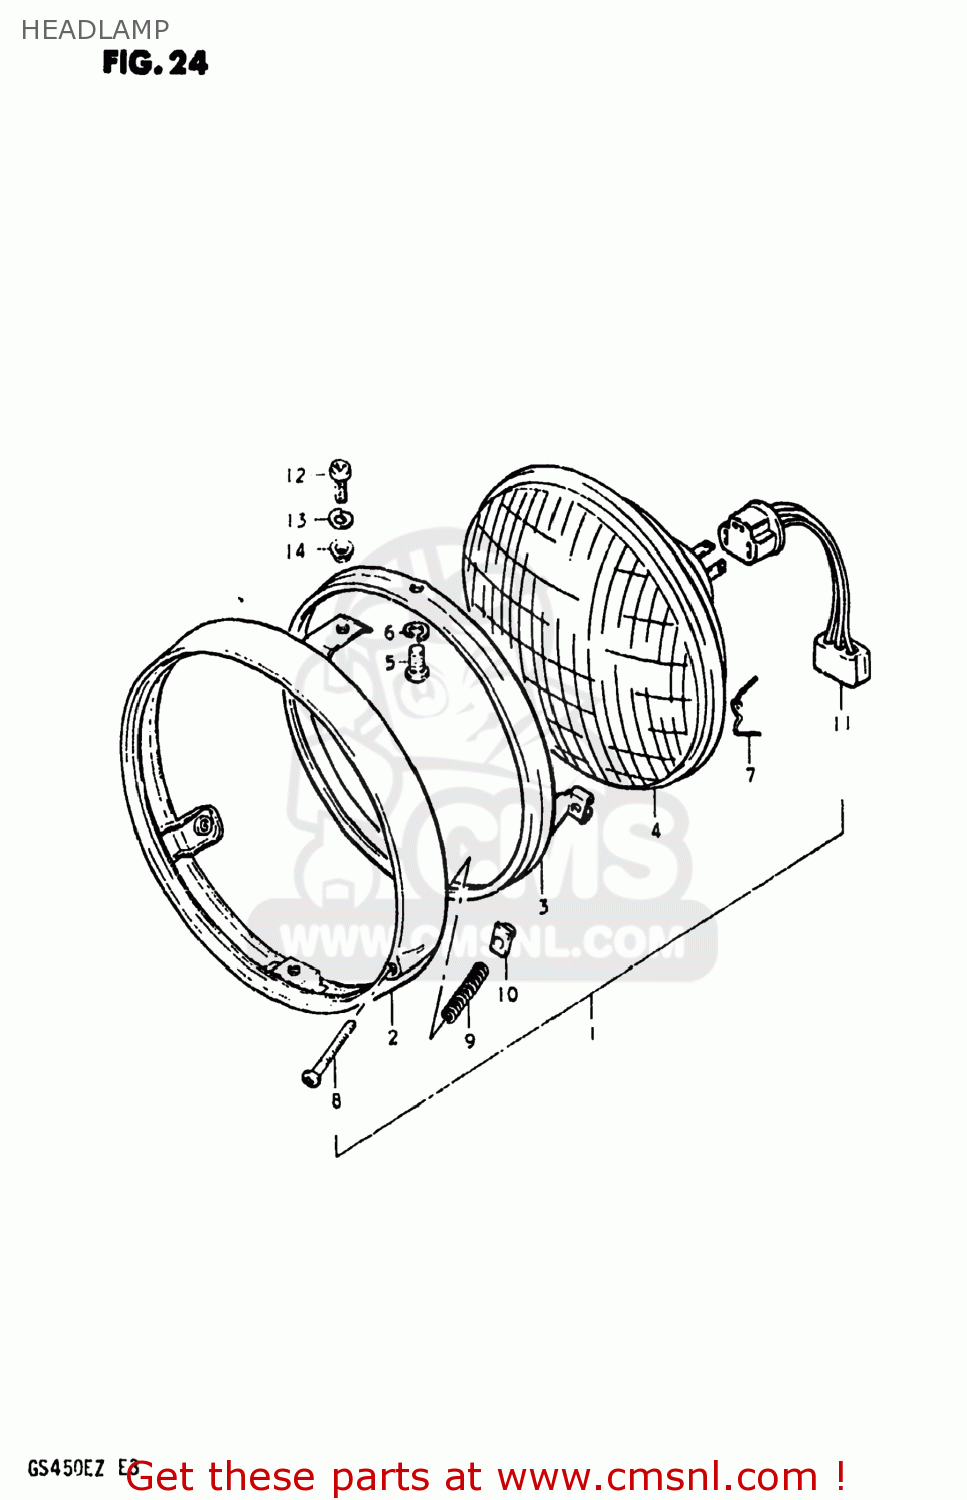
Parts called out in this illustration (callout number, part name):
1	HEADLAMP ASSEMBLY
2	RIM,HEADLAMP
3	RETAINER,HEADLAMP
4	LAMP UNIT
5	SCREW
6	LOCK WASHER
7	SPRING
8	SCREW,HEADLAMP ADJUST
9	SPRING
10	NUT
11	LEAD WIRE,HEADLAMP
12	SCREW
13	WASHER,LOCK
14	WASHER
